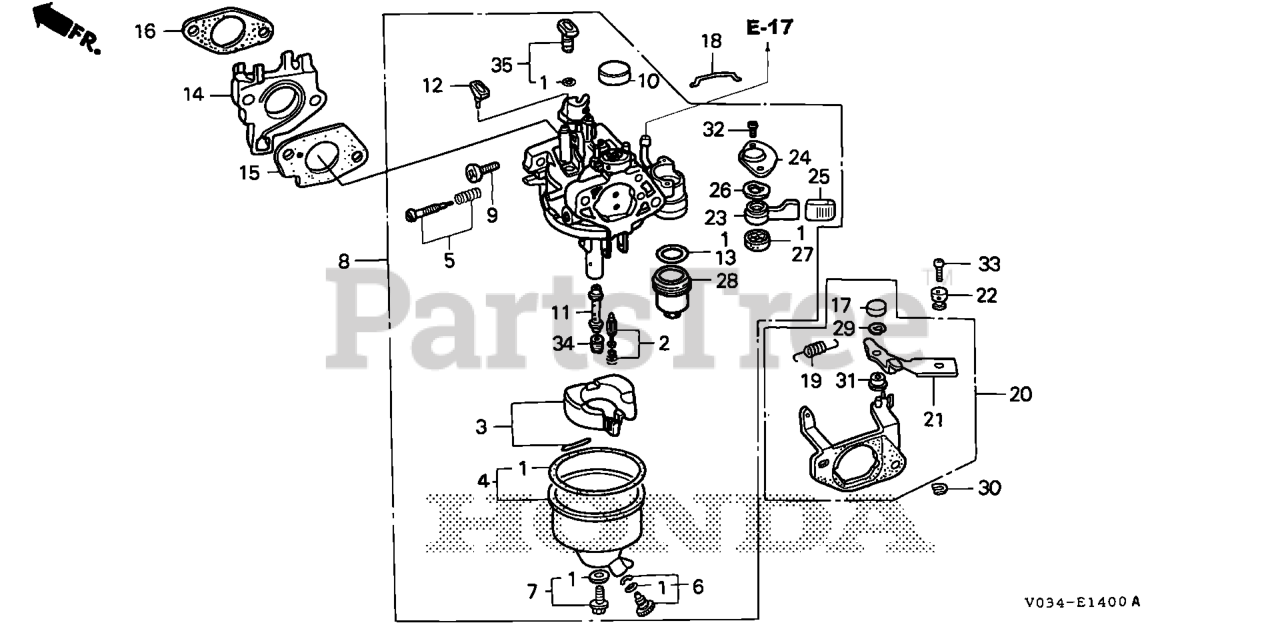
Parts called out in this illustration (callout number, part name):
1	GASKET SET (CARBURETOR NO.)
2	VALVE SET, FLOAT
3	FLOAT SET
4	CHAMBER SET, FLOAT (CARBURETOR NO.)
5	SCREW SET (Honda Code 4219879). (CARBURETOR NO.)
6	SCREW SET, DRAIN (CARBURETOR NO.)
7	SCREW SET B
7	SCREW SET
8	CARBURETOR ASSY. (BE80E A)
9	SCREW, THROTTLE STOP
10	CAP, CHOKE LEVER DUST
11	NOZZLE, MAIN
12	COLLAR, SET
13	GASKET, FUEL STRAINER CUP
14	INSULATOR, CARBURETOR
15	GASKET, CARBURETOR
16	GASKET, INSULATOR Use up to Engine SN 2949254.
17	CAP, CHOKE LEVER
18	ROD, CHOKE
19	SPRING, THROTTLE RETURN
20	STAY ASSY., CHOKE CONTROL (REMOTE)
21	LEVER, CHOKE
22	HOLDER, WIRE
23	LEVER, VALVE
24	PLATE, LEVER SETTING (CARBURETOR NO.)
25	CAP, LEVER
26	SPRING, PETCOCK LEVER (CARBURETOR NO.)
27	GASKET, VALVE
28	CUP, FUEL STRAINER
29	E-RING (4MM)
30	CIRCLIP (5MM) Use from Engine SN 2327377.
31	BUSH, CHOKE LEVER
32	SCREW, PAN (3X6)
33	SCREW, PAN (4X6)
34	JET, MAIN (#95) Use up to Engine SN BE37B A.
34	JET, MAIN (#98) Use up to Engine SN BE50A A.
34	JET, MAIN (#92) (CARBURETOR NO.)
34	JET, MAIN (#95) (CARBURETOR NO.)
34	JET, MAIN (#98) (CARBURETOR NO.)
34	JET, MAIN (#98) Use from Engine SN BE87A A to BE87A A.
35	JET SET, PILOT (#35)
